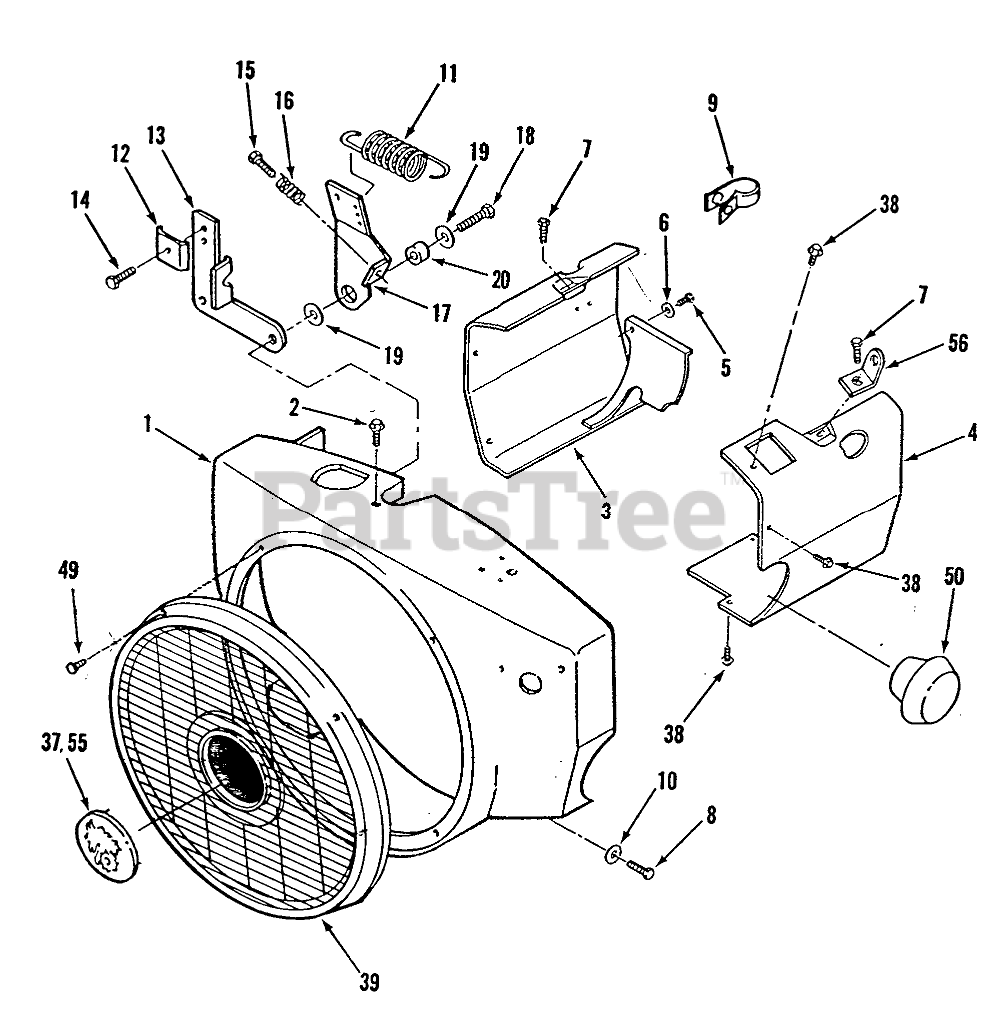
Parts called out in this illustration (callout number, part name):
1	Blower Housing
2	Screw, Cap-Hex. Hd.
3	Cylinder Air Housing
4	Cylinder Air Housing
5	Screw, Cap-Hex Hd.
6	Washer, Flat
7	Wash. Hd. Screw 5/16-18 x 3/4
8	Screw, Cap-Hex Hd.
9	Camp, Wire-Alternator Leads
10	Washer, Flat
11	Spring, Governor
12	Cable Clamp
13	Bracket Cable
14	ST Screw nr. 10-32 x 1/2
15	Screw, Tapping Hex Head
16	Spring Idle Setting
17	Arm-Governor Control
18	Screw-Cap Hex Washer Hd.
19	Washer, Flat
20	Bushing Control Arm
37	Black Nylon Bushing
38	Screw, Cup Hex Washer Hd.
39	Stationary Guard
49	Wash. Hd. Screw 1/4-20 x 3/8
50	Hole Plug
55	Nameplate Logo
56	Lifting Bracket
